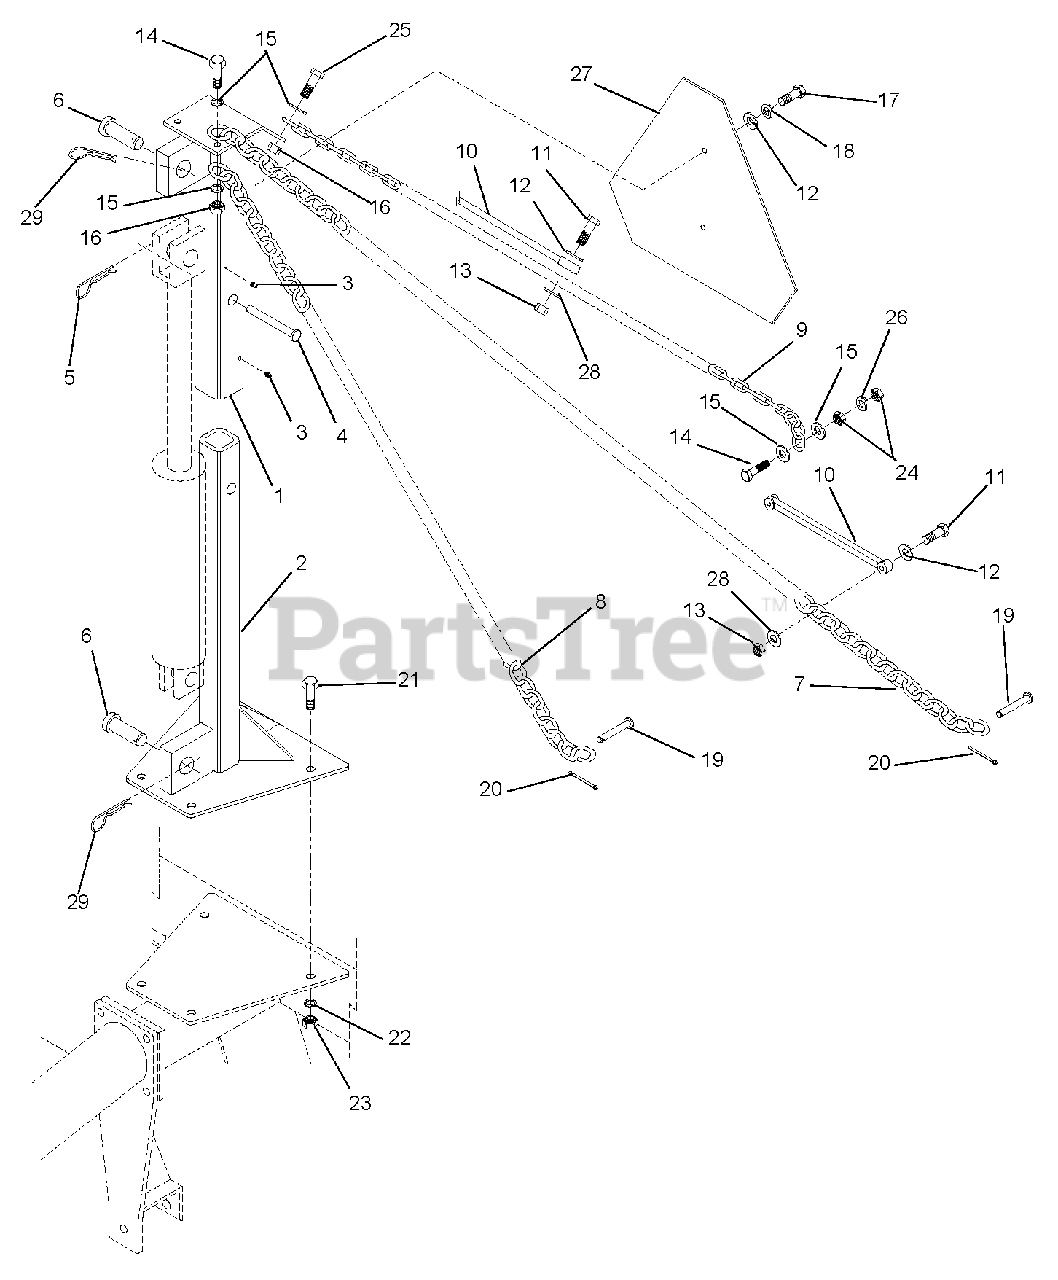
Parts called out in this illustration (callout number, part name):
1	Weldment, Outer Lift Tube
2	Weldment, Inner Lift Post
3	Fitting, Grease .187 Drive
4	Pin, Clevis .625 x 4
5	Pin, Presto Spring Clip
6	Pin, Clevis 1 x 2.25
7	Chain, Outer Front Lift
8	Chain, Inner Front Lift
9	Chain, Rear Lift
10	Strap, Tarp 8.25-Inch No Hook
11	Bolt, Hex .25-20 x 1.50
12	Washer, Flat .25
13	Nut, Hex .25-20 CP Nylock
14	Cap Screw, Hex Head .375-16 x 1.5
15	Washer, Flat .375
16	Nut, Nyloc .375-16 CP
17	Cap Screw, Hex Head .25-20 x .75
18	Washer, Lock .25 CP
19	Pin, Clevis .375 x 1.5
20	Pin, Cotter .156 x 1
21	Cap Screw, Hex Head .50-13 x 1.5
22	Washer, Lock .50 CP
23	Nut, Hex .50 CP
24	Nut, Jam .375-16
25	Cap Screw, Hex Head .375-16 x 1.0
26	Washer, Lock .375 CP
27	Sign, Slow-Moving Vehicle
28	Washer, Flat .25 x 1
29	Pin, Cotter .125
